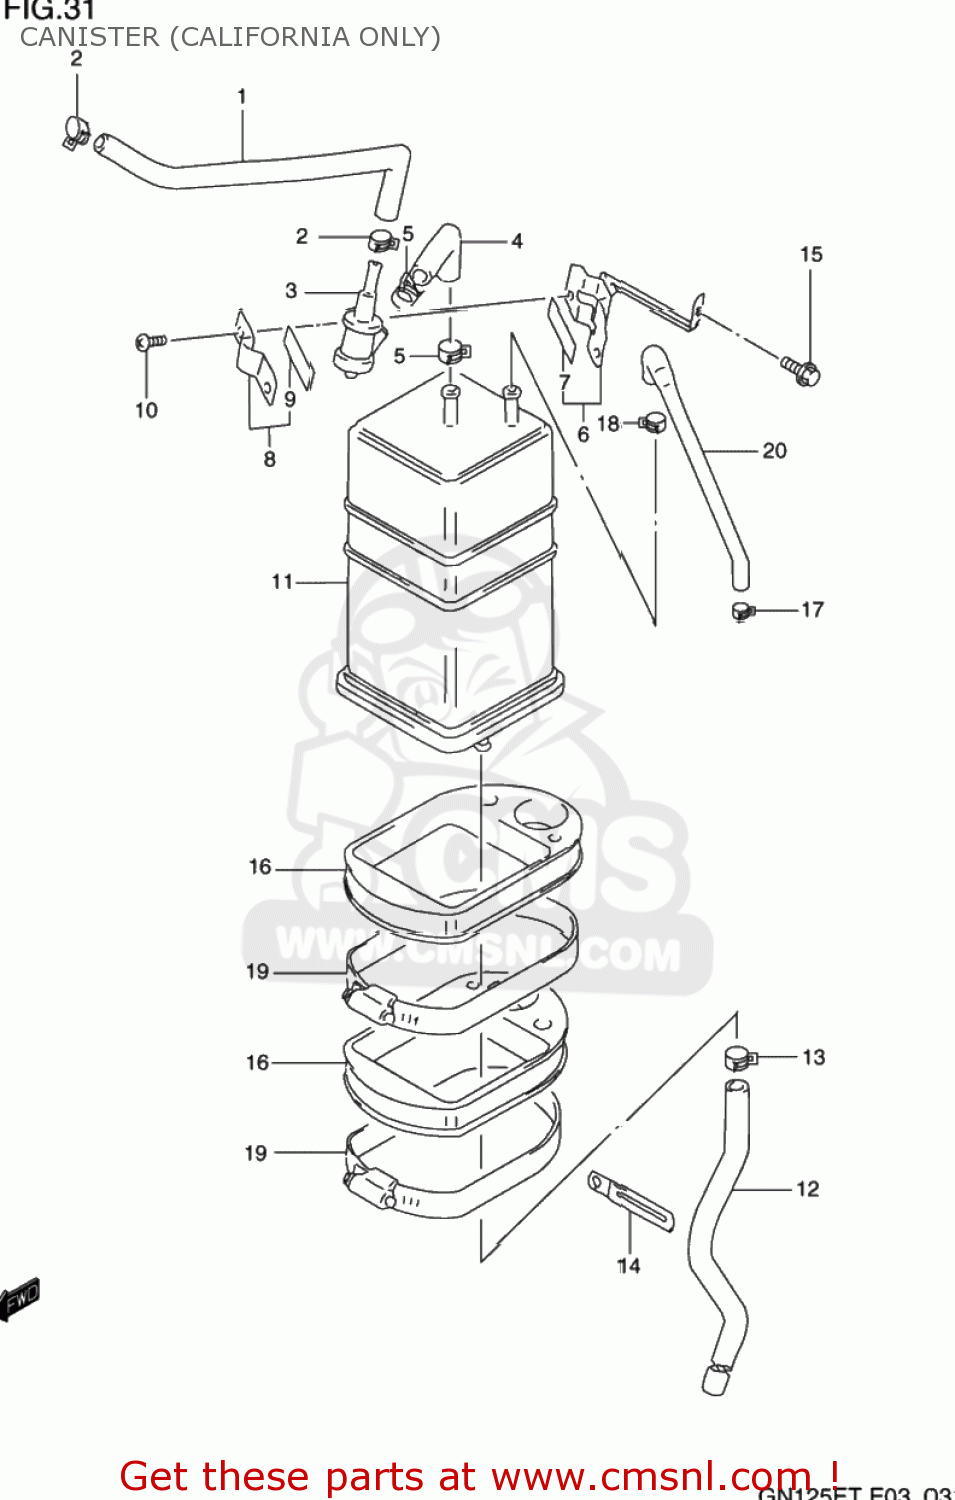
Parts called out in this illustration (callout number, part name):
1	HOSE,TANK & BREATHER VALVE
2	CLIP
3	VALVE,FUEL TANK BREATHER
4	HOSE,BREATHER VALVE & CANISTER
5	CLIP
6	PLATE COMP,TANK BREATHER
7	CUSHION
8	PLATE,FUEL TANK BREATHER NO.2
9	CUSHION
10	SCREW
11	(CA) CANISTER ASSEMBLY
12	HOSE(7X12X600)
13	CLIP
14	CLAMP
15	BOLT
16	CUSHION,CANISTER
17	CLIP
18	CLIP
19	CLAMP
20	HOSE(3.5X7.5X600)
